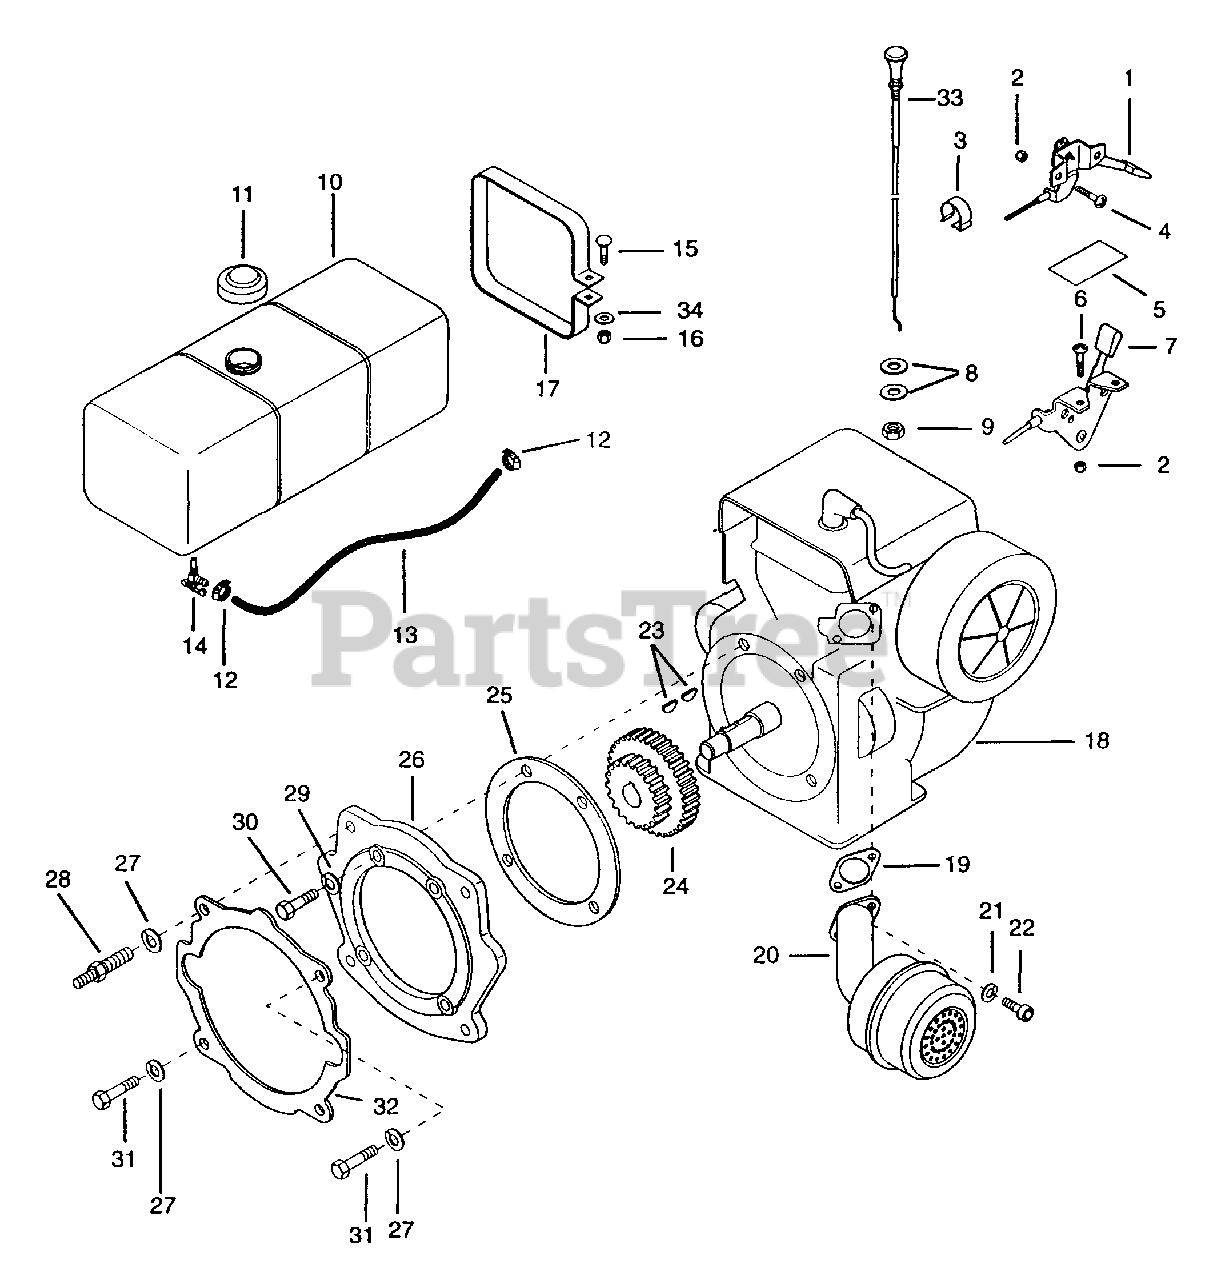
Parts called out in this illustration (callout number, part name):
1	Lever, Control Plated
2	Nut-Locking 10-24
3	Clamp
4	Screw-Machine 10-24 x 1.50
5	Decal, Throttle
6	Screw-Machine 10-24 x .50
7	Lever, Throttle Control Plated
8	Washer-Flat-Steel .406 x .812 x .065
9	Nut-Jam .375-24
10	Assembly, Fuel Tank
11	Cap, Gas Tank
12	Hose Clamp
13	Ft. Gas Line-Bulk
14	Valve & Strainer
15	Bolt-Round Head Square Neck.25-20 x 1.75
16	Nut-Locking-Nylon .250-20 Grade 2
17	Strap, Fuel Tank
18	Engine, 12 HP Electric Magnum
19	Gasket, Exhaust
20	Muffler, 12 HP
21	Washer-Lock .313 x .078
22	Screw-Cap .31-18 x .75
23	Key-Woodruff .16 x .63
24	Gear, 10/12 DP 21/30 Teeth
25	Gasket, Engine to Adaptor
26	Adapter, Engine
27	Washer-Lock .438 x .133
28	Stud
29	Washer-Lock .375 x .155
30	Bolt-Hex .375-16 x 1.00 Grade 5
31	Bolt-Hex .44-14 x 1.25 Grade 5
32	Gasket, Chassis to Adapter
33	Lever, Choke Control Plated
34	Washer-Flat-Steel .281 x .620 x .065
